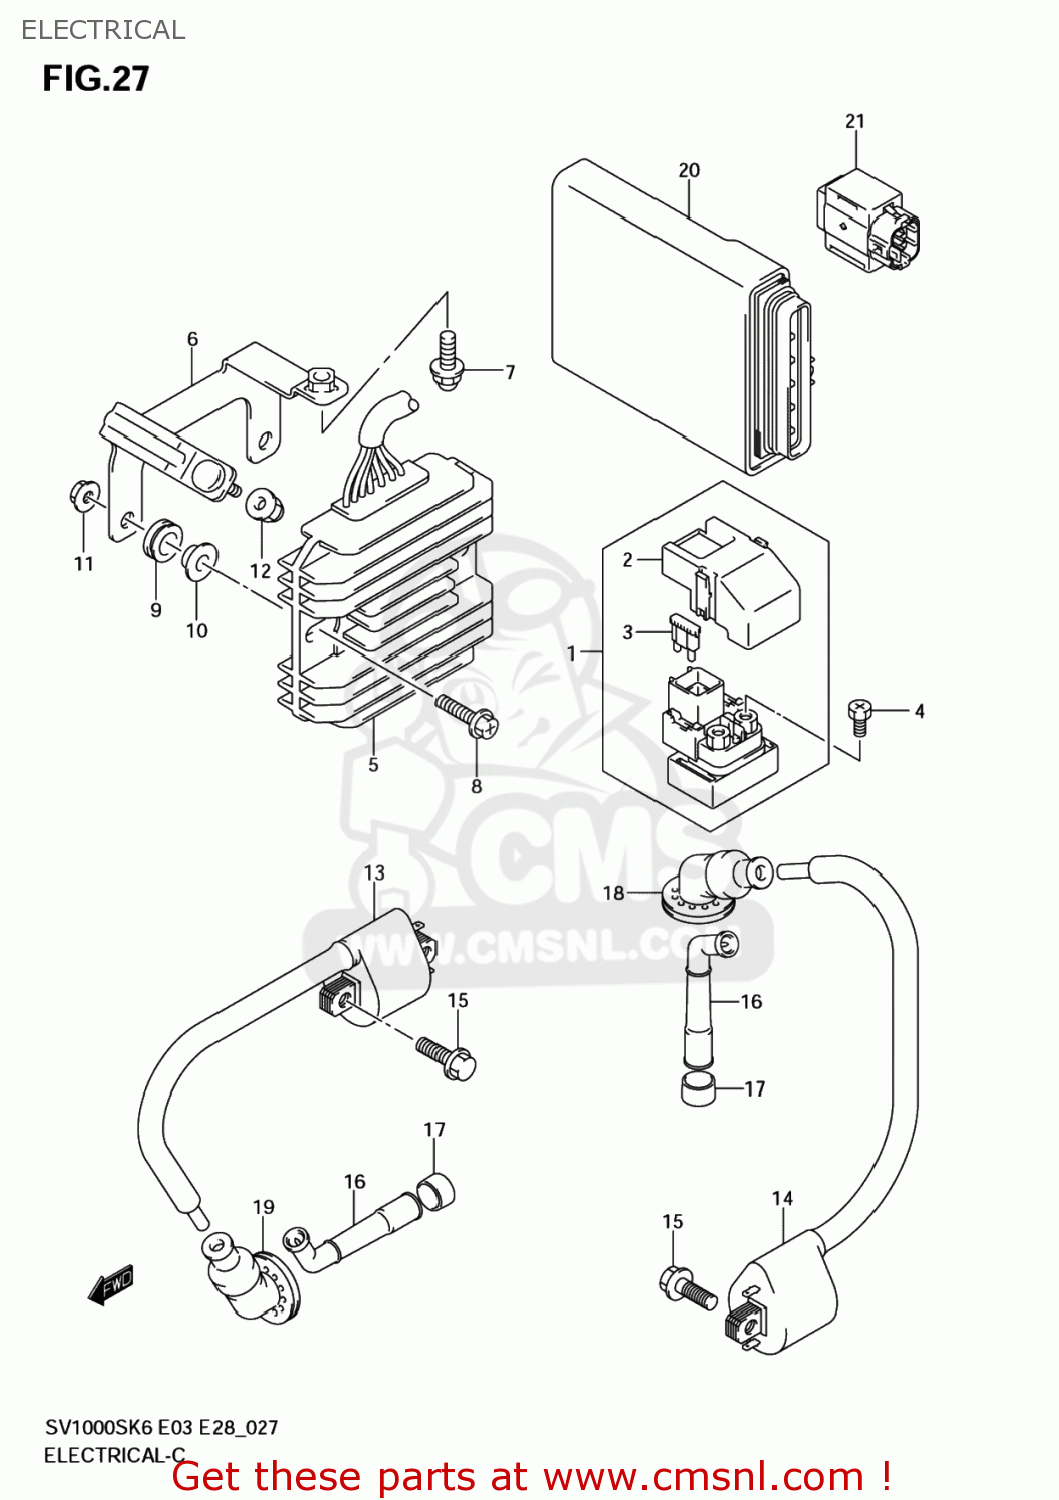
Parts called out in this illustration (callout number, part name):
1	RELAY ASSY,STARTING MOTOR
2	COVER
3	FUSE(30A)
4	SCREW(6X8)
5	RECTIFIER ASSY
6	BRACKET,RECT FTG
7	BOLT(6X15)
8	SCREW
9	CUSHION
10	SPACER(6.2X8.4X6.9)
11	NUT
12	NUT
13	COIL ASSY,IGNITION
14	COIL ASSY,IGNITION
15	BOLT
16	CAP ASSY,SPARK PLUG
17	SEAL,SPARK PLUG CAP
18	SEAL,HIGH TENSION CORD RR
19	SEAL,HIGH TENSION CORD FR
20	CONTROL UNIT,FI
21	SENSOR ASSY,FUEL CUT
